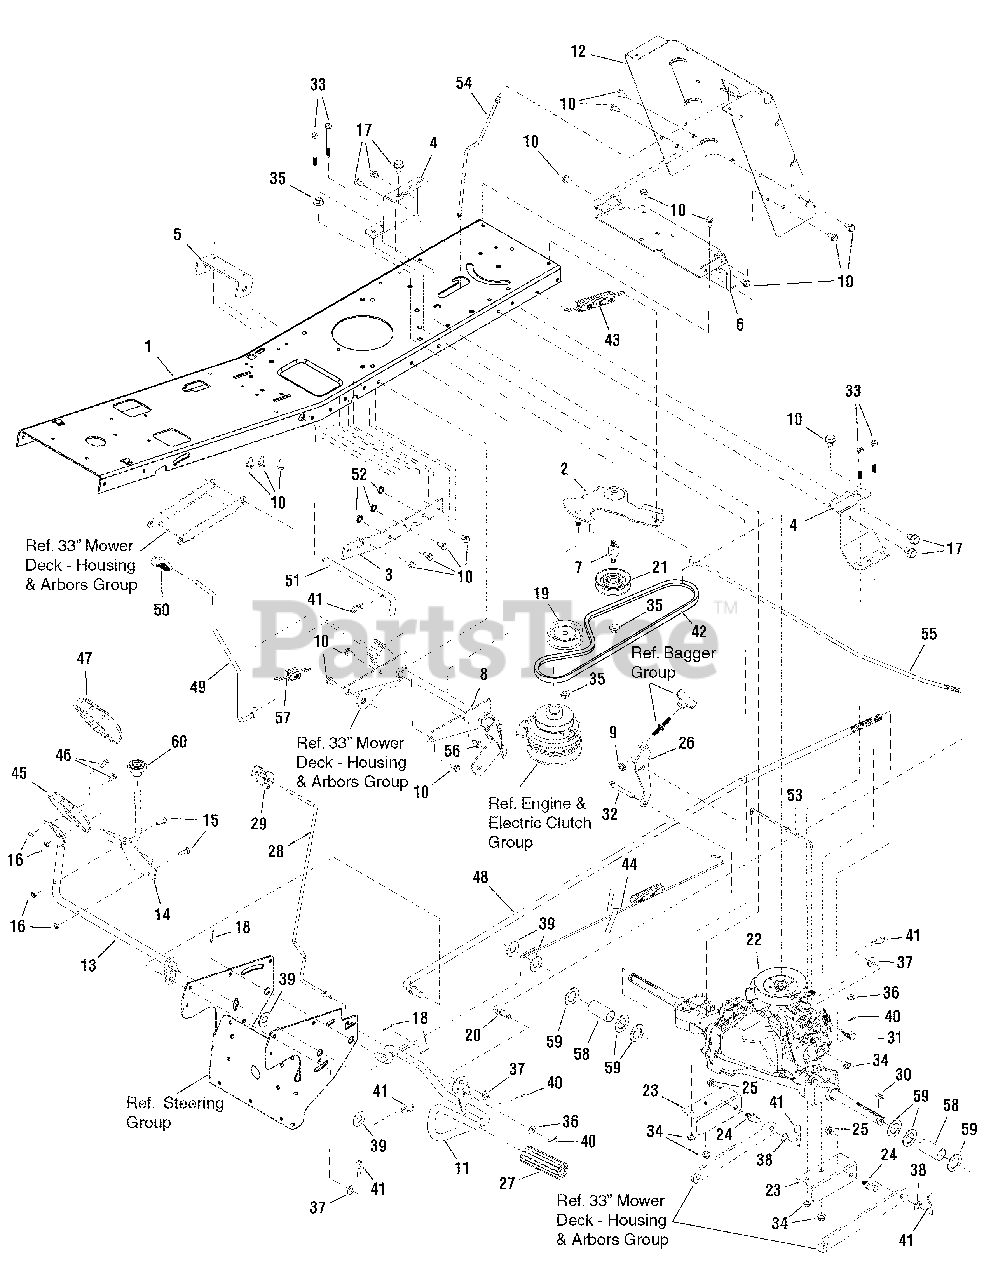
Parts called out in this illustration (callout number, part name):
1	FRAME
2	IDLER PULLEY ARM ASSY
3	REINFORCEMENT PLATE
4	BRACKET, Transaxle
5	BRACKET, Front Hanger Pivot
6	PLATE, Hitch
7	IDLER STUD
8	LIFTER ASSEMBLY
9	NUT, 5/16-18 Hex Flange Lock
10	CAPSCREW, 5/16-18 x 3/4
11	CLUTCH & BRAKE PEDAL ASSEMBLY
12	PLATE, Rear
13	HYDRO ARM ASSY
14	REVERSE PEDAL ASSY
15	BOLT, Carriage, 1/4 - 20 x 1
16	NUT, 1/4 - 20 Centerlock
17	SCREW, 5/16-18 x 0.50
18	PIN, COTTER
19	IDLER PULLEY, Backside
20	NUT, Adjusting
21	IDLER PULLEY, Fixed
22	TRANSMISSION, Hydro Gear
23	REAR HANGER BRACKET, R.H.
24	PIN, Threaded Shoulder, 3/8-16 x 1-1/2
25	NUT, Hex Flange 3/8-16
26	TORQUE STRAP BRACKET
27	PEDAL, Clutch and Brake
28	ROD, Parking Brake
29	KNOB, Parking Brake
30	KEY, Square
31	NUT, Adjusting
32	BOLT, Hex, 5/16-18 x 2-1/2
33	BOLT, Hex-Head 5/16-18 x 3
34	NUT, Hex Flange Lock, 5/16-18
35	NUT, Flange Lock, 3/8-16
36	WASHER, Flat, 3/4
37	WASHER, Flat 3/8
38	WASHER, Flat, .81 x .550 x 16GA
39	WASHER, 0.641 x 1.38
40	PIN, Cotter, 3/4
41	HAIR PIN, .56D-.092T
42	BELT, Drive, 33"
43	SPRING, Extension
44	Spring, Brake Extension
45	PEDAL, Hydro
46	BOLT, Carriage 1/4-20 x 0.63
47	PAD, Hydro Pedal
48	ROD, Shift Link
49	LEVER, Lift Deck
50	GRIP, .50 Black
51	PIN, Front Hanger
52	NUT, Hex Flange 5/16-18
53	ROD, Roll Release
54	ROD, Battery
55	ROD, Clutch Hydro
56	SCREW, Self Tap 5/16-18 x 7/8
57	SPRING, Extension
58	SPACHER
59	WASHER, Flat, 3/4 x 1-1/4 x 16GA
60	PEDAL PAD, Hydro Reverse
